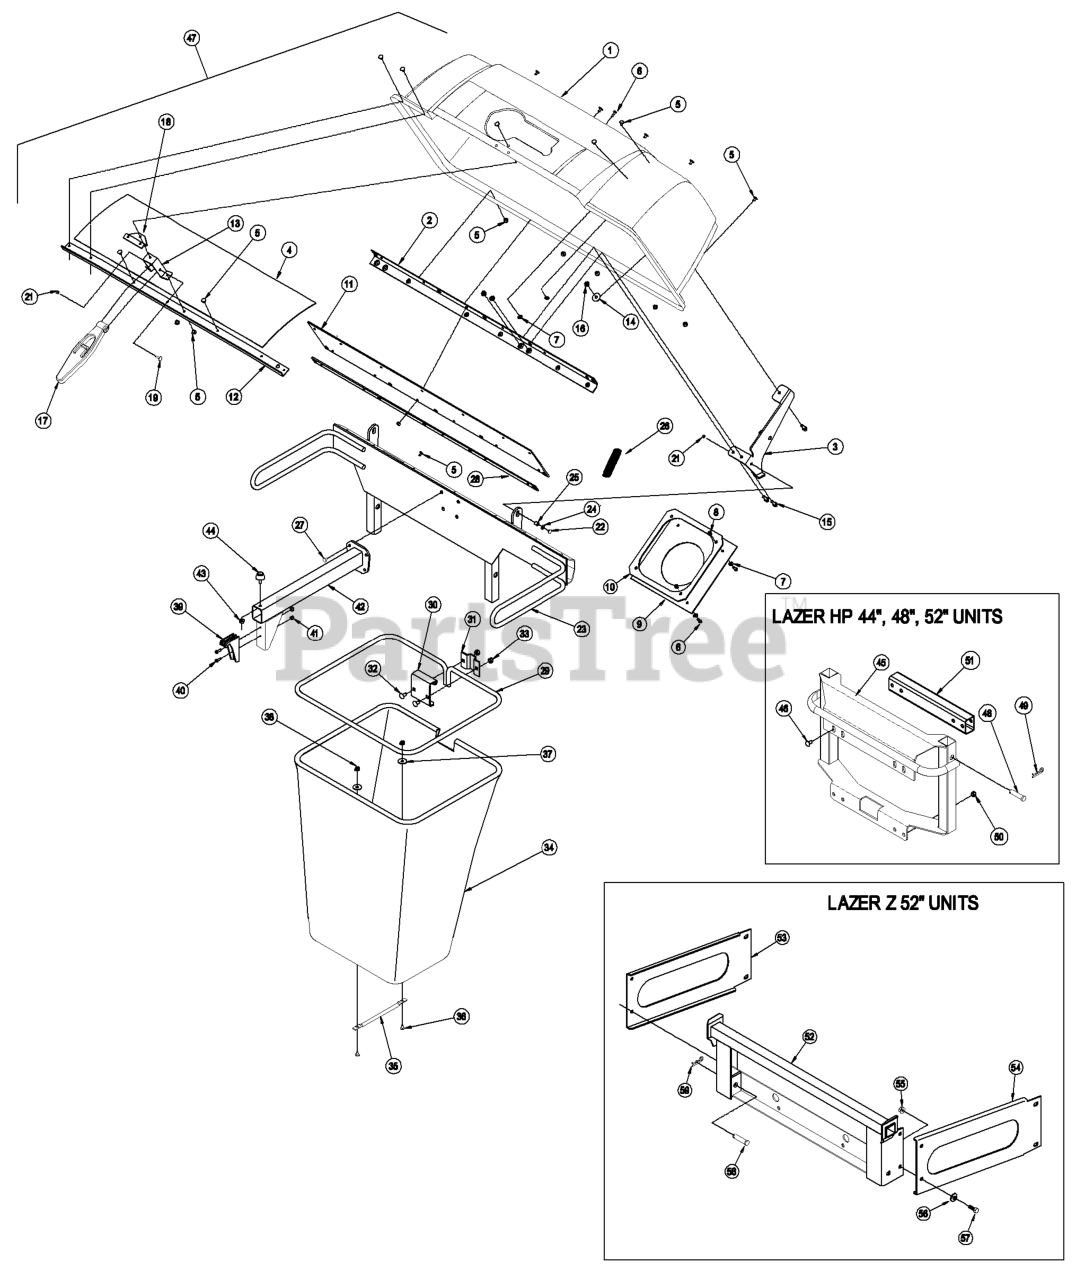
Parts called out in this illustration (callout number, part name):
2	STIFFENER-BAGGER, TOP
3	HINGE ASM
4	SCREEN-BAGGER
5	RIVET-BLIND
6	SCREW-HEAD, TRUSS
7	WASHER-FLAT
8	NUT-LOCK, NI
9	SEAL-CHUTE
10	CLAMP-SEAL
11	SEAL
12	SUPPORT-SCREEN
13	ANCHOR-LATCH
15	SCREW-HH
18	REINFORCEMENT-LATCH
19	SCREW-HH
21	NUT-LOCK, NI
22	SCREW-HH
24	WASHER-FLAT
26	SPRING-EXTENSION
27	SCREW-HH
28	PLATE-BACKING
29	FRAME-BAG
30	HANGER-BAG
32	BOLT-CARR
33	NUT-LOCK, NI
35	HANDLE-BAG
36	BOLT-CARR
38	NUT-LOCK, NI
40	SCREW-PPH
45	BAGGER MOUNT ASM
46	SCREW-HH
47	ASM, HOOD
48	PIN-CLEVIS
49	PIN-COTTER
51	TUBE,SPACER
52	MOUNT-BAGGER
54	BRACKET-FRAME, RH
55	NUT-HHF, WHIZ
56	WASHER-BELLEVILLE
57	SCREW-HH
58	PIN-CLEVIS
